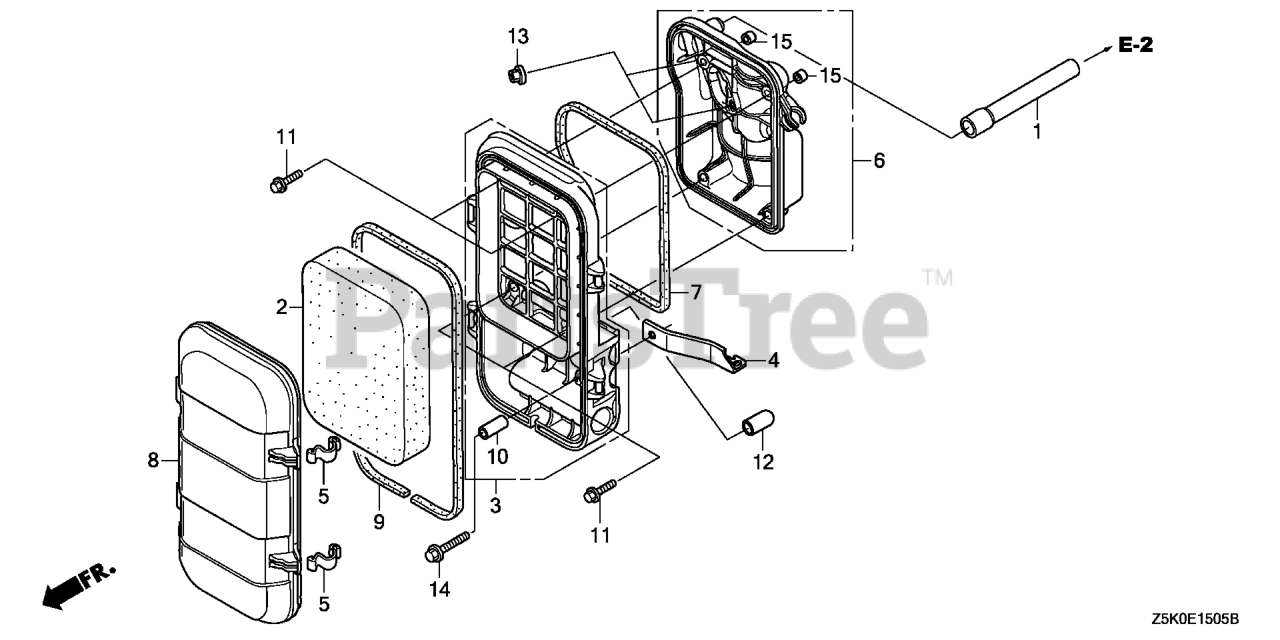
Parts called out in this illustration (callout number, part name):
1	TUBE, BREATHER
2	ELEMENT, AIR CLEANER
3	HOUSING, AIR CLEANER
4	STAY, AIR CLEANER
5	SPRING, AIR CLEANER HOUSING LID
6	BASE, AIR CLEANER
7	SEAL, AIR CLEANER HOUSING
8	COVER, AIR CLEANER
9	SEAL, AIR CLEANER COVER
10	COLLAR, AIR CLEANER
11	BOLT, FLANGE (5X18)
12	CAP, SEALING
13	NUT, FLANGE (6MM)
14	BOLT, FLANGE (6X32)
15	COLLAR, AIR CLEANER
